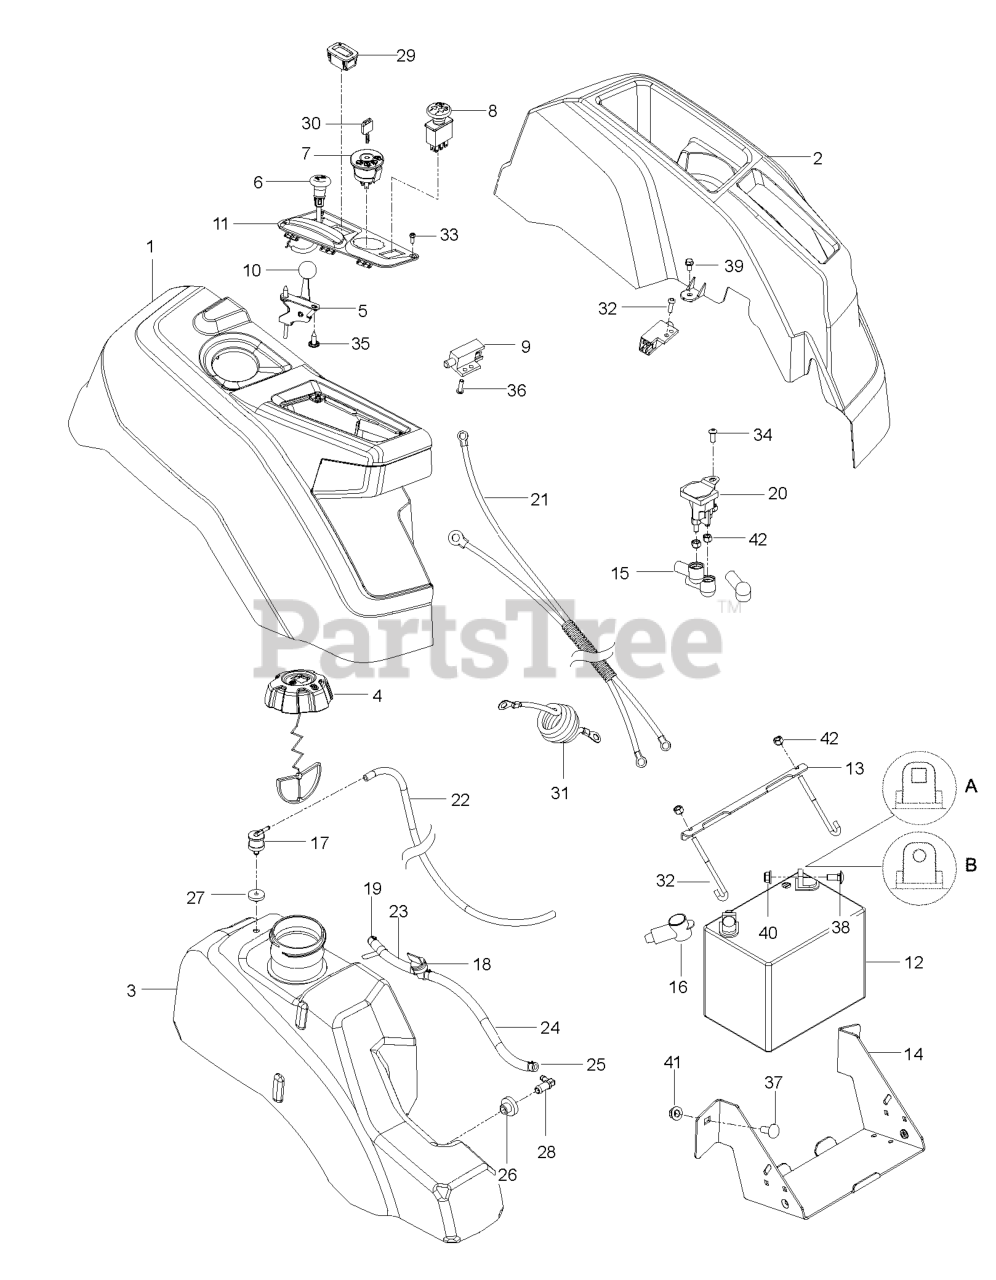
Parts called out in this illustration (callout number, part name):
1	CONSOLE.ASSY.RZ.REFRESH.RH
2	CONSOLE.LH.ASM
3	Tanks
4	FUEL CAP
4	CAP ASSY FUEL 3" GRAY
5	THROTTLE CABLE
6	CHOKE.PUSH-IN.STYLE
7	RP IGNITION SWITCH
8	RP SWITCH.PTO.TERMINAL.STD.RED
9	SWITCH.INTLK.RZ.RFRSH.BUTTON
10	KNOB.ROUND.BALL.BLACK
11	CONTROL.PANEL.RZ.REFRESH.RH
12	BATTERY, 12 V 300 AMP DRY
12	BATTERY.DRY.30.AMP
13	BRACKET.PNT.MOUNT.BATTERY.EDIP
14	BOX.PNT.BATTERY.RZ.EDIP
15	TERMINAL COVER
17	VALVE.FUEL.CHECK
18	FUEL VALVE
19	FUEL.HOSE.SHUT.OFF.ASM.10".18"
20	SOLENOID.STARTER.BRASS.PLUNGER
21	HARNESS.BTTRY.CABLE.RZ.REFRESH
22	HOSE.3/16".VAPOR.LINE.50"LGTH
23	HOSE.1/4".LOW.PERM.FUEL.LN.10"
24	HOSE 1/4" LOW PERMEATION FUEL
25	HOSE CLAMP
26	BUSHING OUTLET T
27	GROMMET.ROV.SENTEC
28	STEM FUEL TANK
29	GUAGE.SRVCMNDR.HRMTR.
30	KEY MLD GEN DELTA
31	CABLE BATTERY POS RZ
32	HOOK.J.BATTERY
33	SCREW 6-19X.437
34	SCR 1/4-20 X 5/8 BTN SKT HD ZD
35	SCREW.PAN.HEAD.#10
36	SCREW.BUTTONHD.10-24X1/2.(2 2)
36	SCR #10-24 X .75 SKT HD BLK
37	RHSNB 3/8C X 1
38	BOLT.HEX.1/4.X.3/4.DICHROMATE
38	RP BOLT 5/16-18 X3/4 ZN/YEL GR
38	GSPW Bolts
39	SCREW
40	5/16-18 NYLOC FLANGE NUT
40	Hardware
40	NUT HEXAGON FLANGE 5/16-18 ST
41	NUT 3/8-16 HEX FLG NYLOC ZD
42	NUT.1/4-20.HEX.NYLOC.ZD
